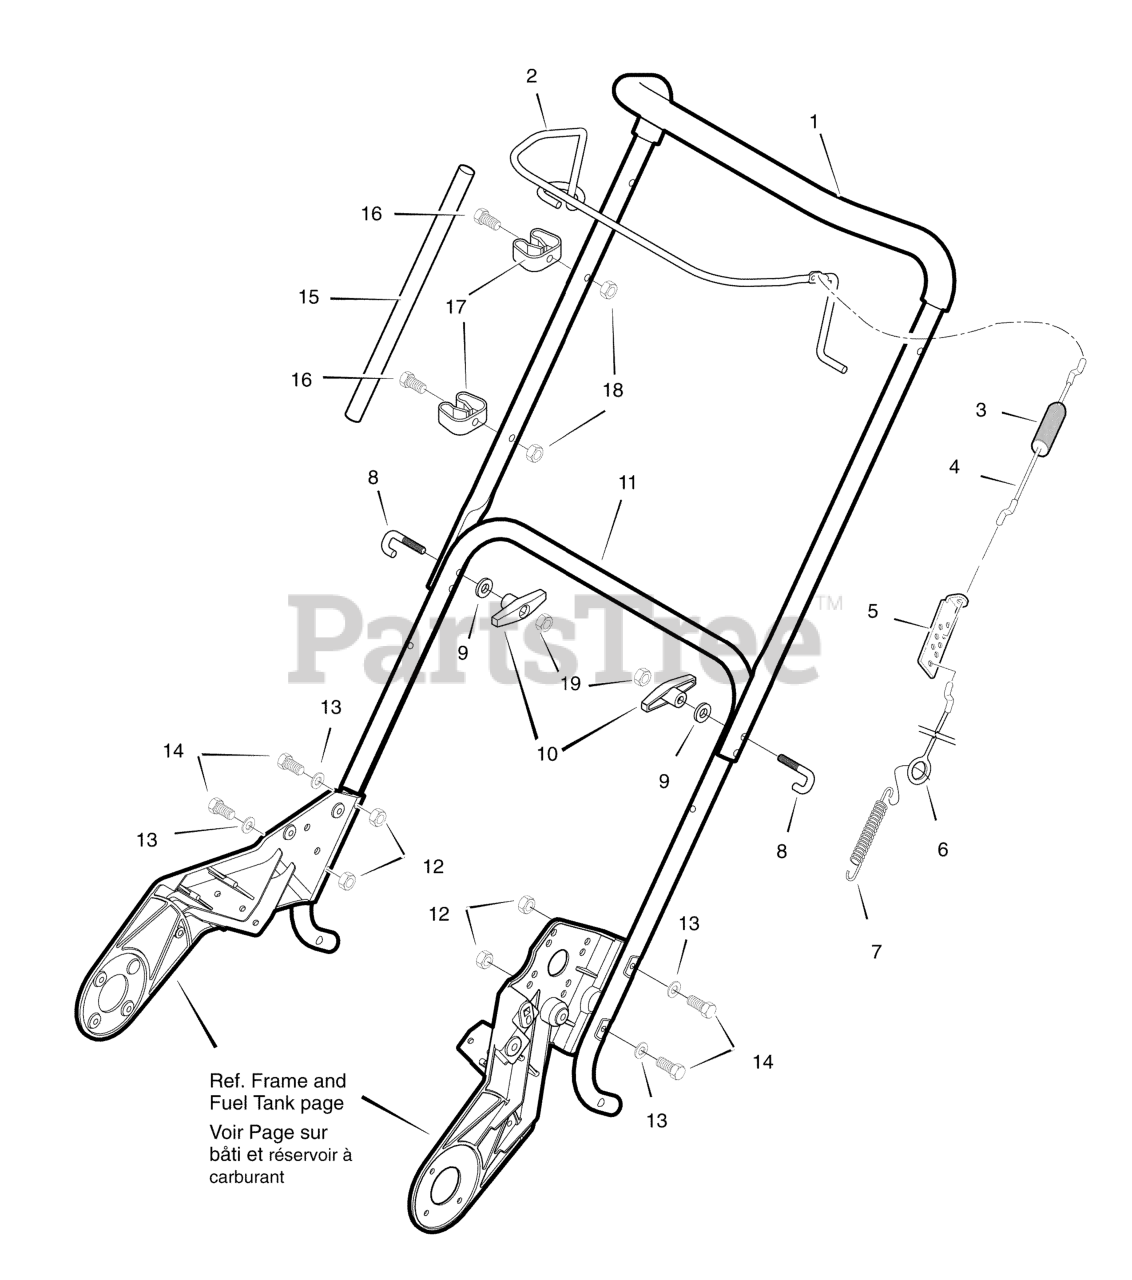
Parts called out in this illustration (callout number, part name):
1	Handle, Upper (Foam)
2	Control, Bail
3	Boot, Clutch Spring
4	Cable, Upper Control
5	Bracket, Control Adjust
6	Cable, Lower Control
10	Knob, Wing
11	Handle, Lower
12	Nut
13	Washer
14	Screw, 1/4-20 x 1.25
15	Tool, Clean-out
17	Clip, Retainer
19	Nut 5/16-18
